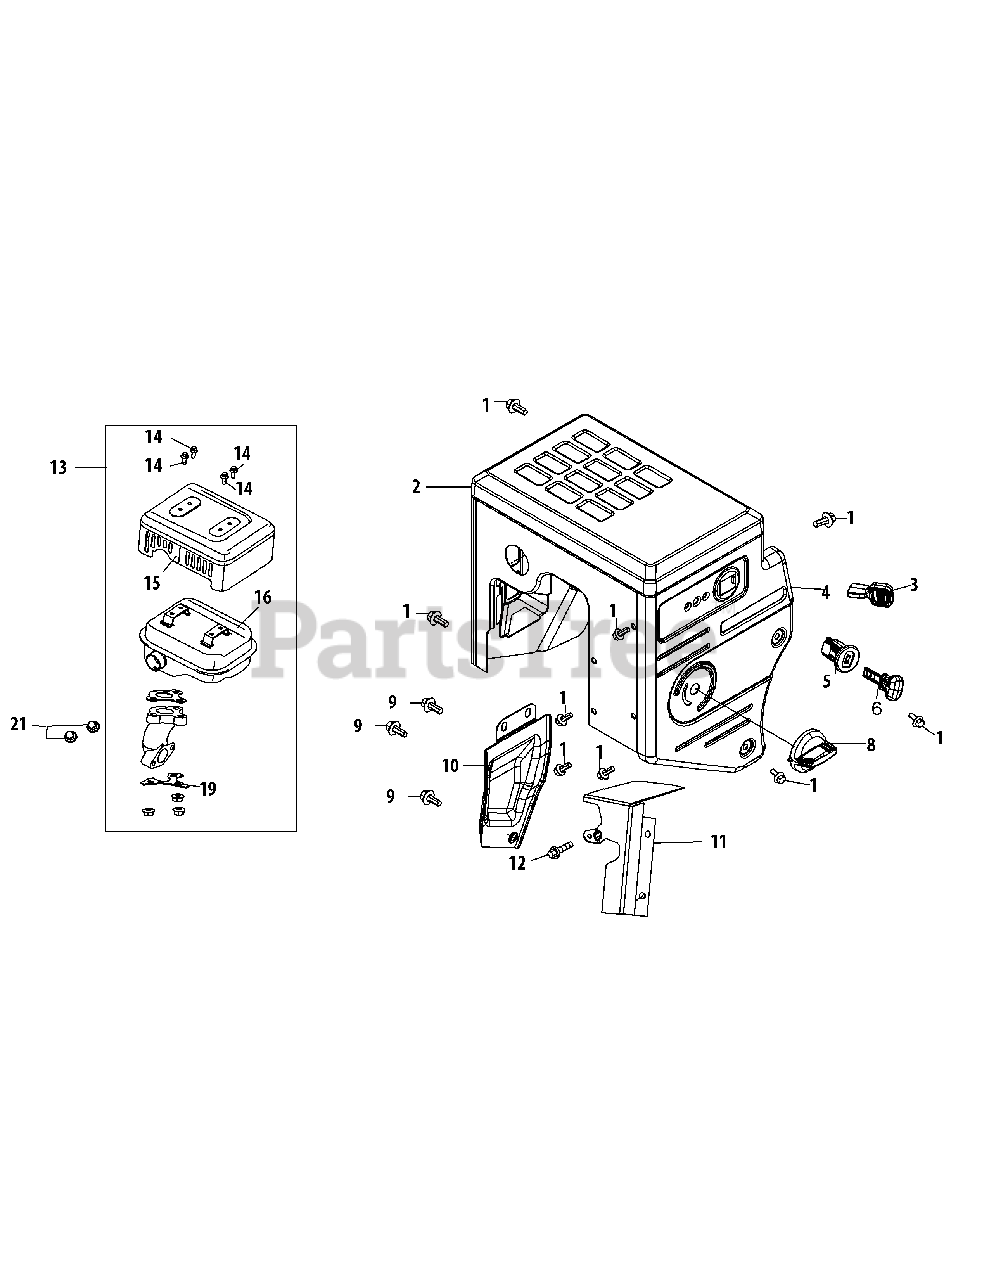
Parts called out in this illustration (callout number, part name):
1	BOLT M6×12
2	MUFFLER SHIELD
3	THROTTLE CONTROL KNOB
4	CONTROL PANEL
5	ENGINE SWITCH BASE
8	CHOKE KNOB
9	BOLT M6×10
10	EXHAUST PIPE SHIELD
11	CARB ISOLATOR BRACKET
12	BOLT M6×16
13	MUFFLER ASSEMBLY
15	MUFFLER GUARD
16	MUFFLER BODY
